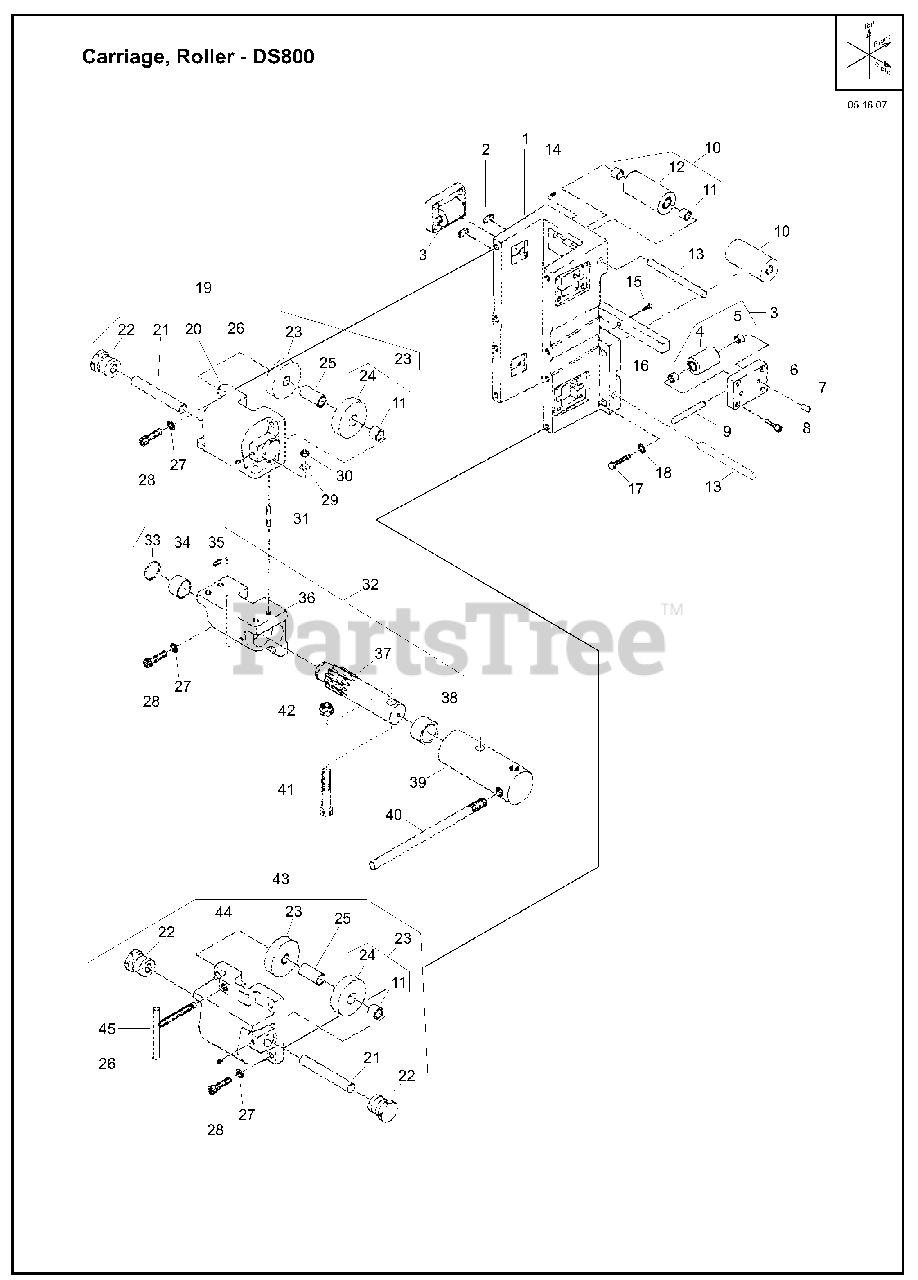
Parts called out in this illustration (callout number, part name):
1	Body, Roller Carriage, Husq Orange
2	Spacer, Rubber, Side Roller
3	Roller, Side - compl
4	Roller, Side
5	Bushing, .252ID x .377OD x .25
6	Housing, Roller Husq Orange
7	Screw, Soc Hd Set, .25-20 X .5 Cup Pt
8	Capscrew, Soc Hd, 10-24 x .75 Gr8
9	Shaft, Side Roller
10	Roller, Carriage - compl
11	Bushing, .377ID x .502OD x .50
12	Roller, Carriage
13	Shaft, Roller
14	Screw, Soc Hd Set, 10-24 x .312 Cup Pt
15	Screw, Fl Hd 8-32 x 3/4" Brass
16	Key, .500 Sq x 5.88"
17	Capscrew, Hex Hd, .375-16 x 1.5
18	Washer, Lock 3/8", Int Tooth
19	Upper Roller Housing - compl
20	Housing, Roller, Top, Husq Orange
21	Shaft, Eccentric Adj. Roller
22	Adjuster, Eccentric Roller
23	Roller, Adjustable – compl
24	Roller, Adjustable
25	Spacer, Roller
26	Screw, Soc Hd Set, .25-20 x .375 Cup Pt
27	Washer, Lock, 5/16 Internal Tooth
28	Capscrew, Soc Hd, .3125-18 x 1.25 Gr8
29	Washer, Flat SAE .25
30	Nut, Hex Jam .25-28
31	Stud, TBE, .25-20 / .25-28 x 1.00
32	Pinion Bracket – compl
33	Retaining Ring, .750 D
34	Bushing, .753ID x .876 OD x .75
35	Screw, Soc Hd Set, .25-20 x .312 Dog Pt
36	Bracket, Pinion, Husq Orange
37	Gear, Pinion, DS 800
38	Bushing, 1.128ID x 1.313OD x .750
39	Hub, Handle
41	Capscrew, Hex Hd, 1/2-13 x 2-1/4
42	Locknut, Fiber .50-13
43	Lower Roller Housing - compl
44	Housing, Roller Lower, Husq Orange
45	Screw, Lock, DS800
